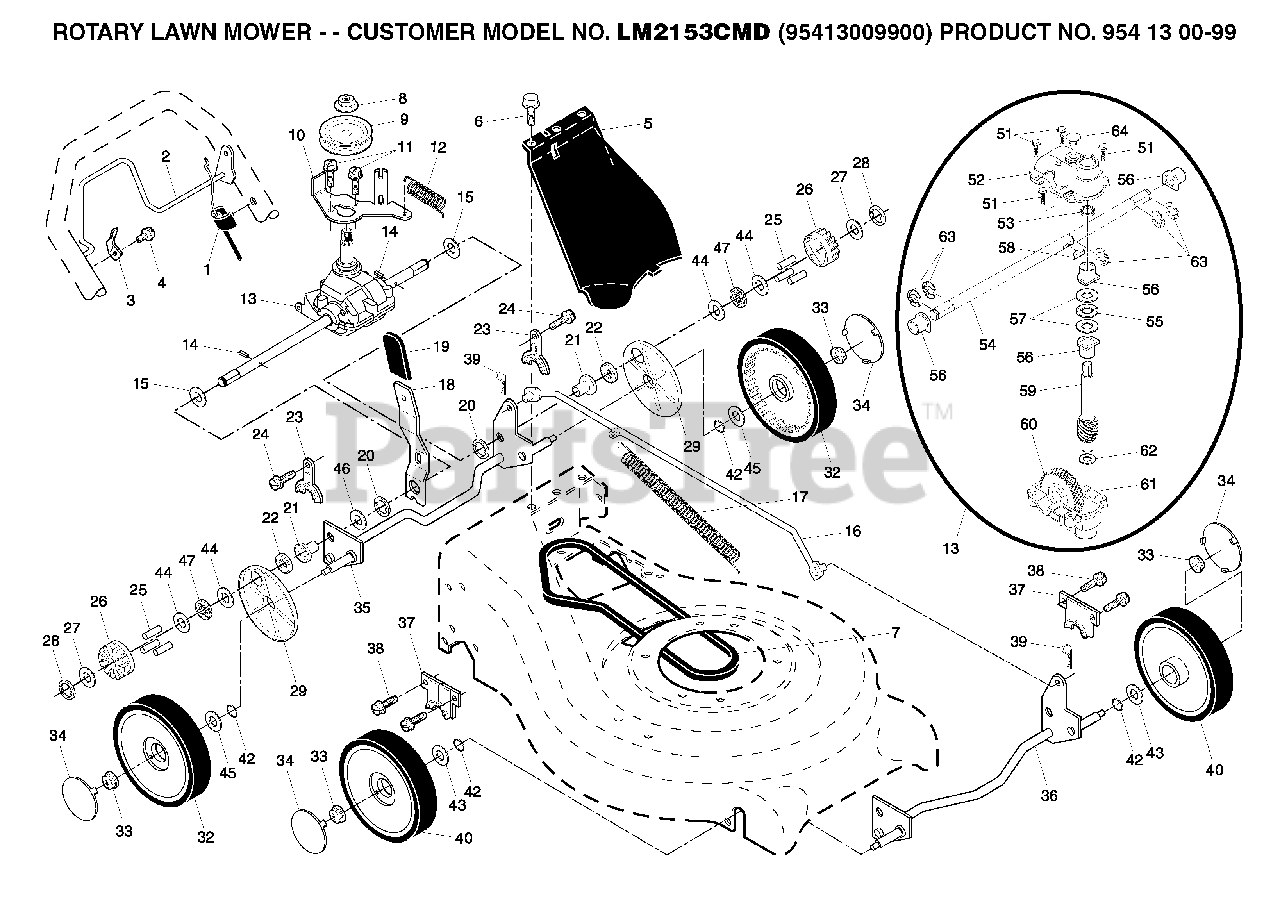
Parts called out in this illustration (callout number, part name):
1	DRIVE CABLE
2	BAIL.CONT.DR.21.RWGD.BLACK
3	DOWNSTOP BRACKET
8	FLANGED LOCKNUT 3/8-16 ZINC
13	TRANSMISSION
14	PIN.SPRING.THRUST
15	THRUST WASHER
16	ROD CONNECTING
17	SPRING
18	SPRING SELECTOR
19	KNOB, SELECTOR SPRING
21	RP BEARING SUPPORT
22	BEARING, BALL
23	BRACKET
26	DRIVE PINION
27	WASHER
28	E-RING 7/16 RE
29	COVER.DUST.WHEEL
32	WHEEL 9X2
33	HEX FLANGE LOCKNT
34	HUBCAP
35	SHAFT.ASM.REAR.TORQUE
37	RETAINER.FRONT.SHAFT
39	RETAINER CLIP
40	FRONT.WHEEL.8X2
42	O-RING
43	WASHER PM
44	BELLEVILLE WASHER
45	WASHER FLUT
52	GEAR CASE, UPPER
54	TRANSMISSION ASM. (WALK)
55	BEARING, NEEDLE, THRUST
57	WASHER, THRUST
58	HI PRO KEY
59	SHAFT GEAR WORM
60	GEAR, HELICAL
61	GEAR CASE, LOWER
62	THRUST WASHER
63	KLIP RING
